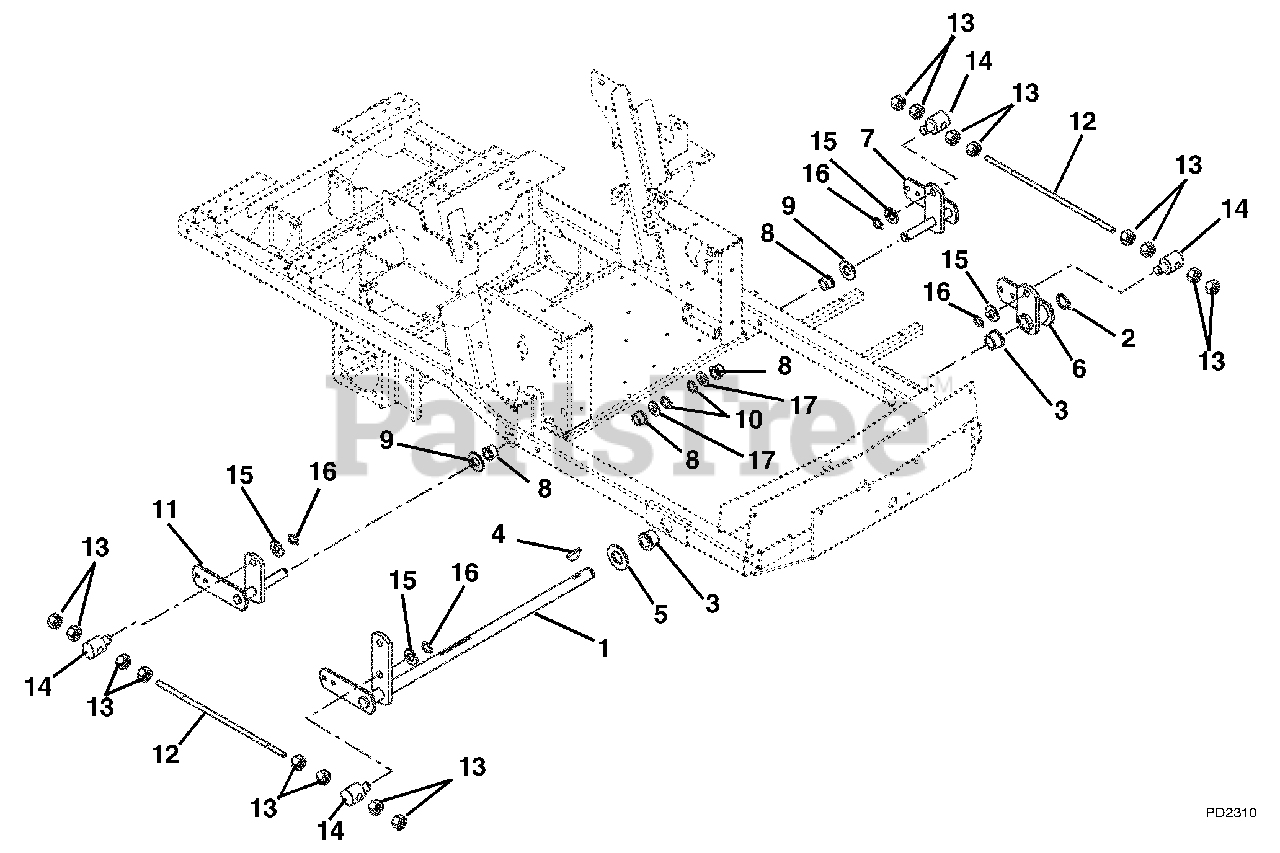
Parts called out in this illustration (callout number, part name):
1	Lift-Mower
2	Ring-Retaining-External 1.00 x .078
3	Bushing-Flange-Nylon 1.020 x 1.385 x .75 x 1.75
4	Key-Woodruff .25 x 1.00
5	Washer-Flat-Steel 1.063 x 2.00 x .134
6	Weldment, Lift Arm-Front
7	Weldment, Rear Lift Arm-Left Hand
8	Bushing-Flange-Nylon .762 x 1.0 x .580 x 1.48
9	Washer-Hardened-Steel .758 x 1.23 x .031
10	Ring-Retaining-External .689 x .077
11	Weldment, Rear Lift Arm- Right Hand
12	Rod-Lift Assist
13	Nut-Jam .50-13
14	Pivot-Mower Lift
15	Washer-Flat-Steel .630 x 1.005 x .062
16	Ring-Retaining-External .625 x 050
17	Washer-Flat-Steel .755 x 1.25 x .125
